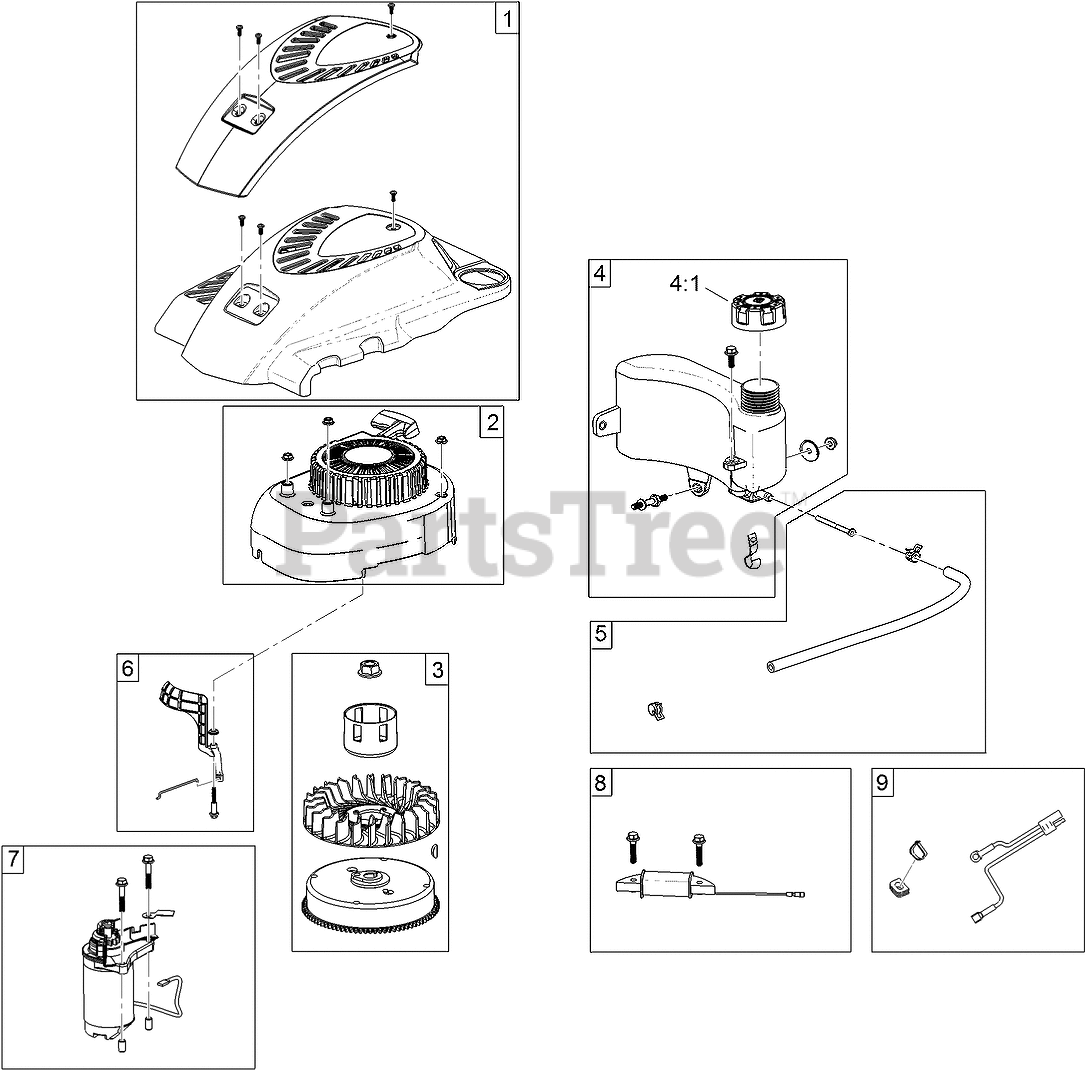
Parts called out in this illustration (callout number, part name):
1	Shroud ASM
2	RECOIL AND BLOWER SHROUD KIT
3	FLYWHEEL AND FAN KIT
4	FUEL TANK KIT (CAP AND HARDWARE)
4:1	CAP-FUEL
5	FUEL LINE KIT
6	AIR VANE CHOKE KIT
7	STARTER KIT
8	ALTERNATOR KIT
9	WIRE HARNESS KIT
